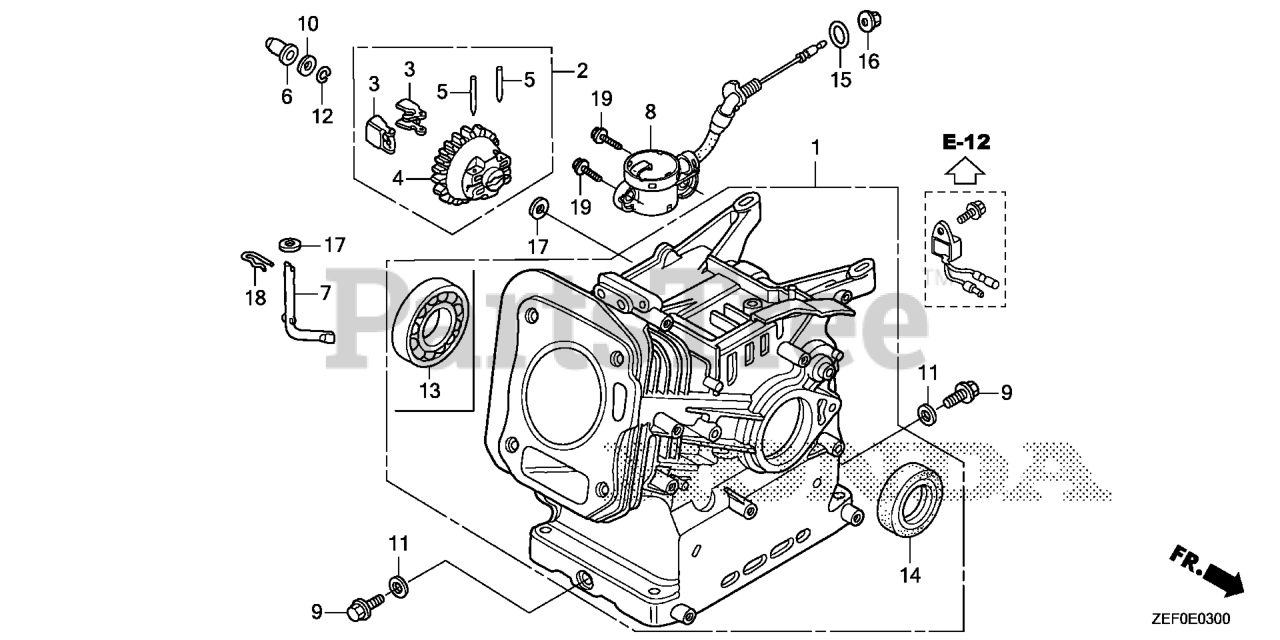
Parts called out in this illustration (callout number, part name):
1	CYLINDER ASSY. (OIL ALERT)
2	GOVERNOR ASSY.
3	WEIGHT, GOVERNOR
4	HOLDER, GOVERNOR WEIGHT
5	PIN, GOVERNOR WEIGHT
6	SLIDER, GOVERNOR
7	SHAFT, GOVERNOR ARM
8	SWITCH ASSY., OIL LEVEL
9	BOLT, DRAIN PLUG
10	WASHER, THRUST (6MM)
11	WASHER, DRAIN PLUG (10.2MM)
12	CLIP, GOVERNOR HOLDER
14	OIL SEAL (25X41X6)
14	OIL SEAL (25X41X6) (ARAI) (NOT AVAILABLE)
15	O-RING (14MM)
16	NUT, FLANGE (10MM)
17	WASHER, PLAIN (6MM)
18	PIN, LOCK (8MM)
19	BOLT, FLANGE (6X12) Use from Engine SN 2086984.
